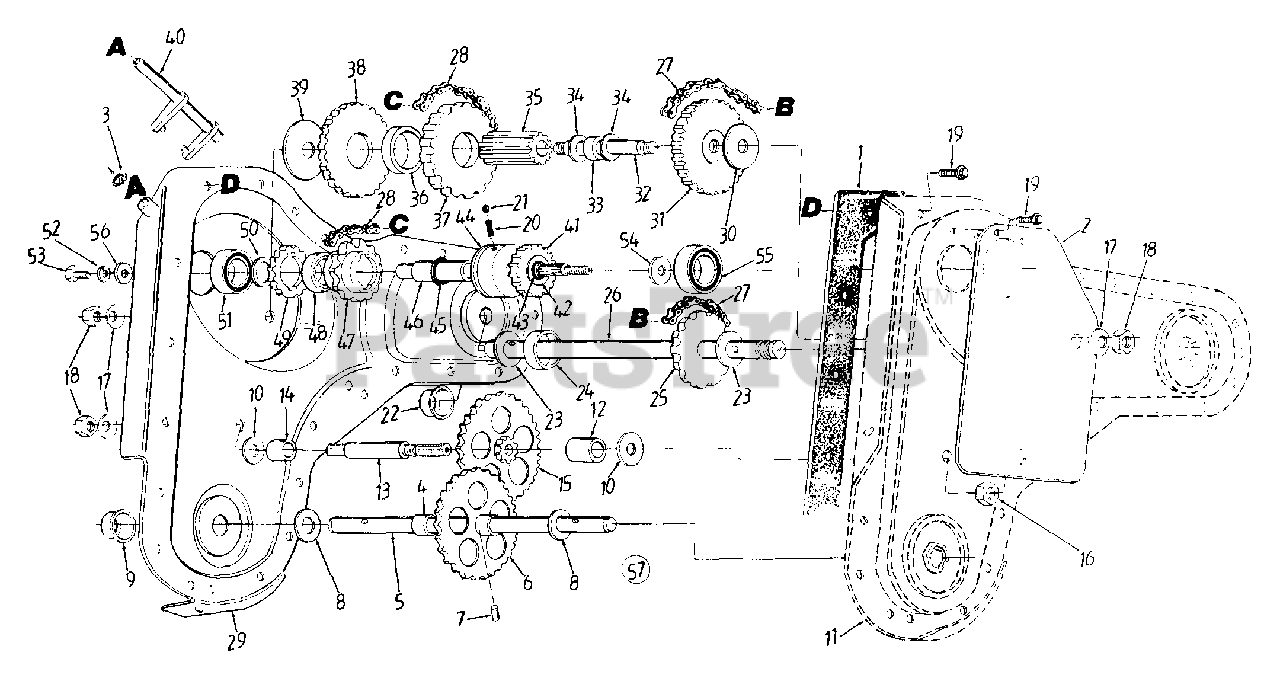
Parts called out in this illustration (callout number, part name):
1	Chain Case Gasket
3	Snap Ring
4	Spacer .735" I.D. x .886" O.D.
5	Wheel Shaft
6	Spur Gear 46T
7	Pin Type "E" Grooved
8	Fl-Wash. .76" I.D. x 1.5" O.D.
9	Dust Cover Ass'y. .75" Shaft
10	Fl-Wash. 7/16" I.D. x 1-3/8" O.D.
13	Jack Shaft 2.06" Lg.
14	Spacer .635" I.D. x 1" O.D. x .37" Thk.
15	Gear Idler Ass'y.
16	Hex Patch L-Nut 7/16-20 Thd.
17	Bell-Wash. .45" I.D. x 1" O.D.
18	Hex Nut 7/16-20 Thd.
19	Hex Wash. Hd. TT-Tap Scr. 1/4-20 x .5" Lg.
20	Spring Detent
21	Ball Detent
22	Dust Cover Ass'y. 1" Shaft
23	Thrust Wash. 1.03" I.D. x 1.62" O.D.
24	Spacer 1" I.D. x 2" O.D. x .5" Thk.
25	18T Sprocket
26	Tine Shaft
27	Chain #50 5/8" Pitch x 52 Links - Endless
28	Chain - #41 1/2" Pitch x 30 Links - Endless
30	Fl-Wash. 7/16" I.D. x 1-3/8" O.D.
31	Gear and Sprocket Ass'y.
32	Jack Shaft 5" Lg.
33	Spacer .636" I.D. x .86" O.D.
34	Fl-Wash. .63" I.D. x .94" O.D.
35	Spur Gear 10T
36	Spacer 1.5" I.D. x 1.76" O.D.
37	Sprocket - #41 Chain
38	Reverse Gear 46T
39	Thrust Wash. .445" I.D. x 1.92" O.D.
40	Shifter Ass'y.
41	Spur Gear 17T
42	Fl-Wash. .69" I.D. x 1.06" O.D.
43	Retaining Ring .669" Shaft
44	Clutch Collar
45	Retaining Ring .875" Shaft
46	Drive Shaft
47	Sprocket 11T
48	Neutral Spacer
49	Spur Gear 16T
50	Fl-Wash. 5/8" I.D. x 1" O.D.
51	Ball Bearing .669" I.D.
52	L-Wash. 1/4" I.D.
53	Hex Bolt 1/4-20 x .62" Lg.
54	Fl-Wash. .635" I.D. x 1" O.D.
55	Ball Bearing
56	Fl-Wash. .281" I.D. x .875" O.D.
57	Gear Case Ass'y. Comp.
